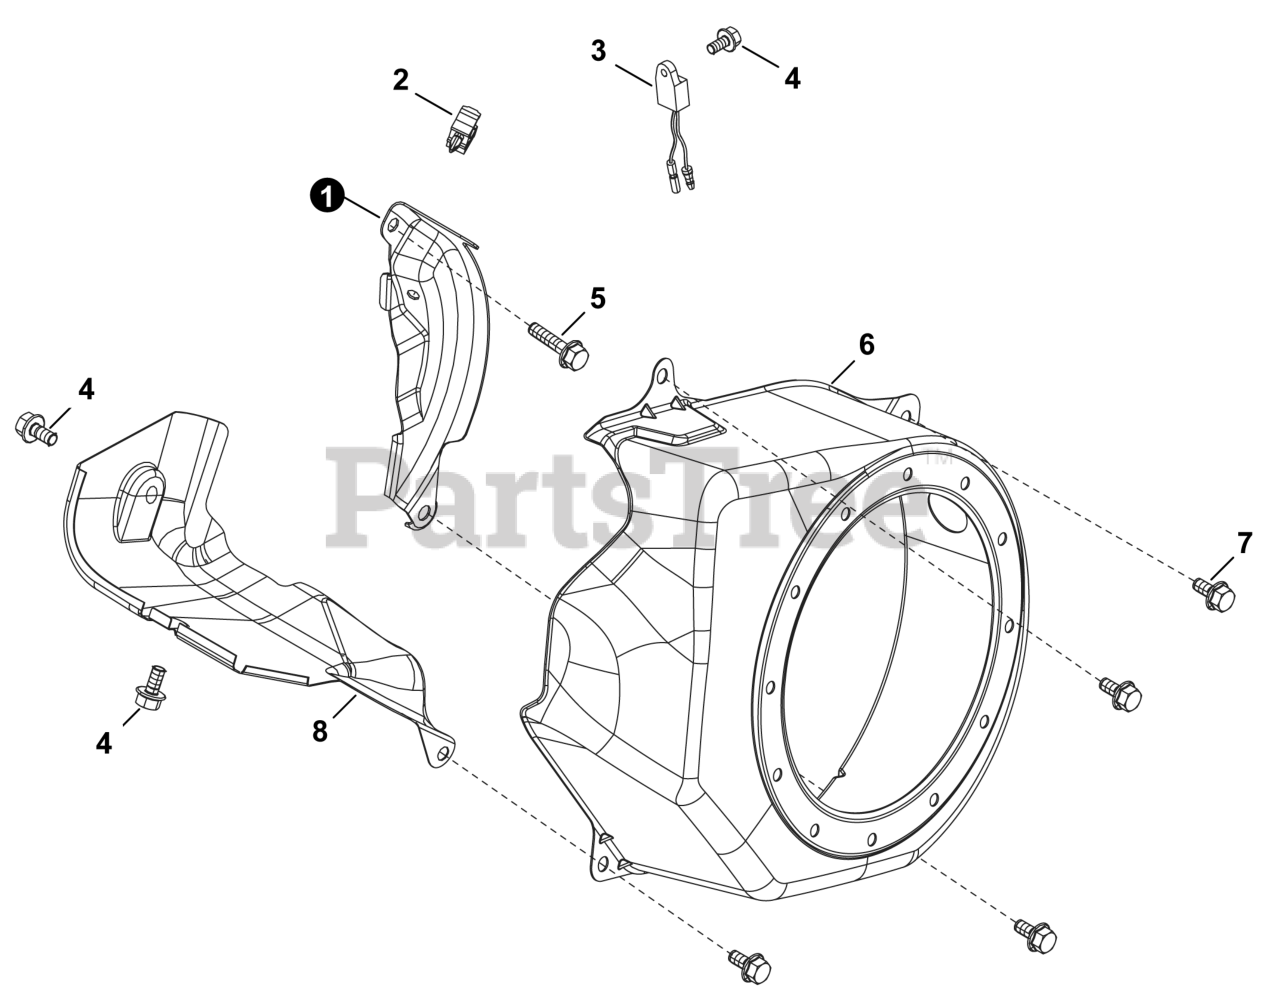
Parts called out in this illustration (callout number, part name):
1	SHIELD,LOWER
3	PROTECTOR, OIL
8	SHROUD, CYLINDER BODY
